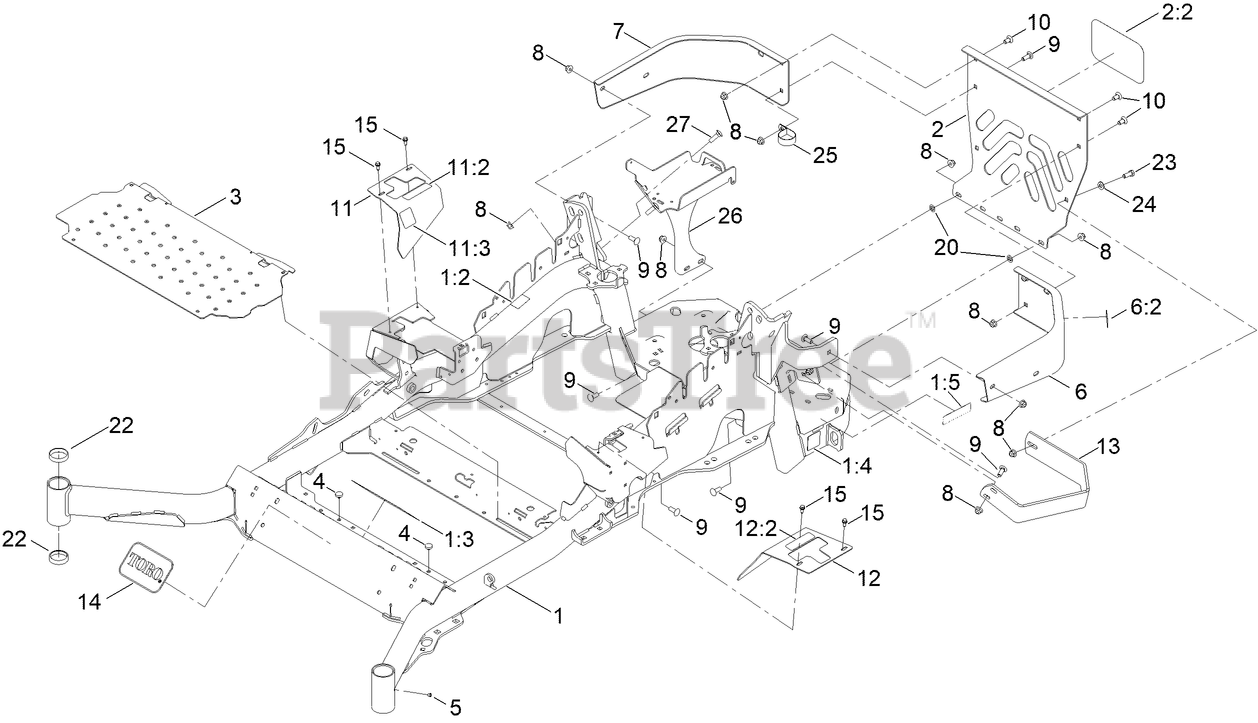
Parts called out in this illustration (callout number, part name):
1	MAINFRAME SERVICE ASM - 72
1:2	DECAL-WARNING
1:3	DECAL-DANGER
1:4	DECAL-HAZARD, PINCHED FINGER
1:5	DECAL-ARRESTOR, SPARK
2	REAR GUARD ASM
2:2	DECAL
3	FLOORPAN
4	BUMPER
6	LH BUMPER ASM
6:2	DECAL-WARNING
7	BUMPER-RH
8	NUT-HF, NI
9	SCREW-CARR
10	SCREW-CARR
11	RH MOTION CONTROL COVER ASM
11:2	DECAL-CONTROL, MOTION
11:3	DECAL-PARK BRAKE, CE
12	LH MOTION CONTROL COVER ASM
12:2	DECAL-CONTROL, MOTION
13	GUARD-MUFFLER
14	DECAL
15	SCREW-HWH
20	NUT-PUSH
22	CUP-BEARING
23	SCREW-HH
24	WASHER-FLAT
25	CLAMP-R
26	BATTERY MOUNT ASM
27	BOLT-CARR
